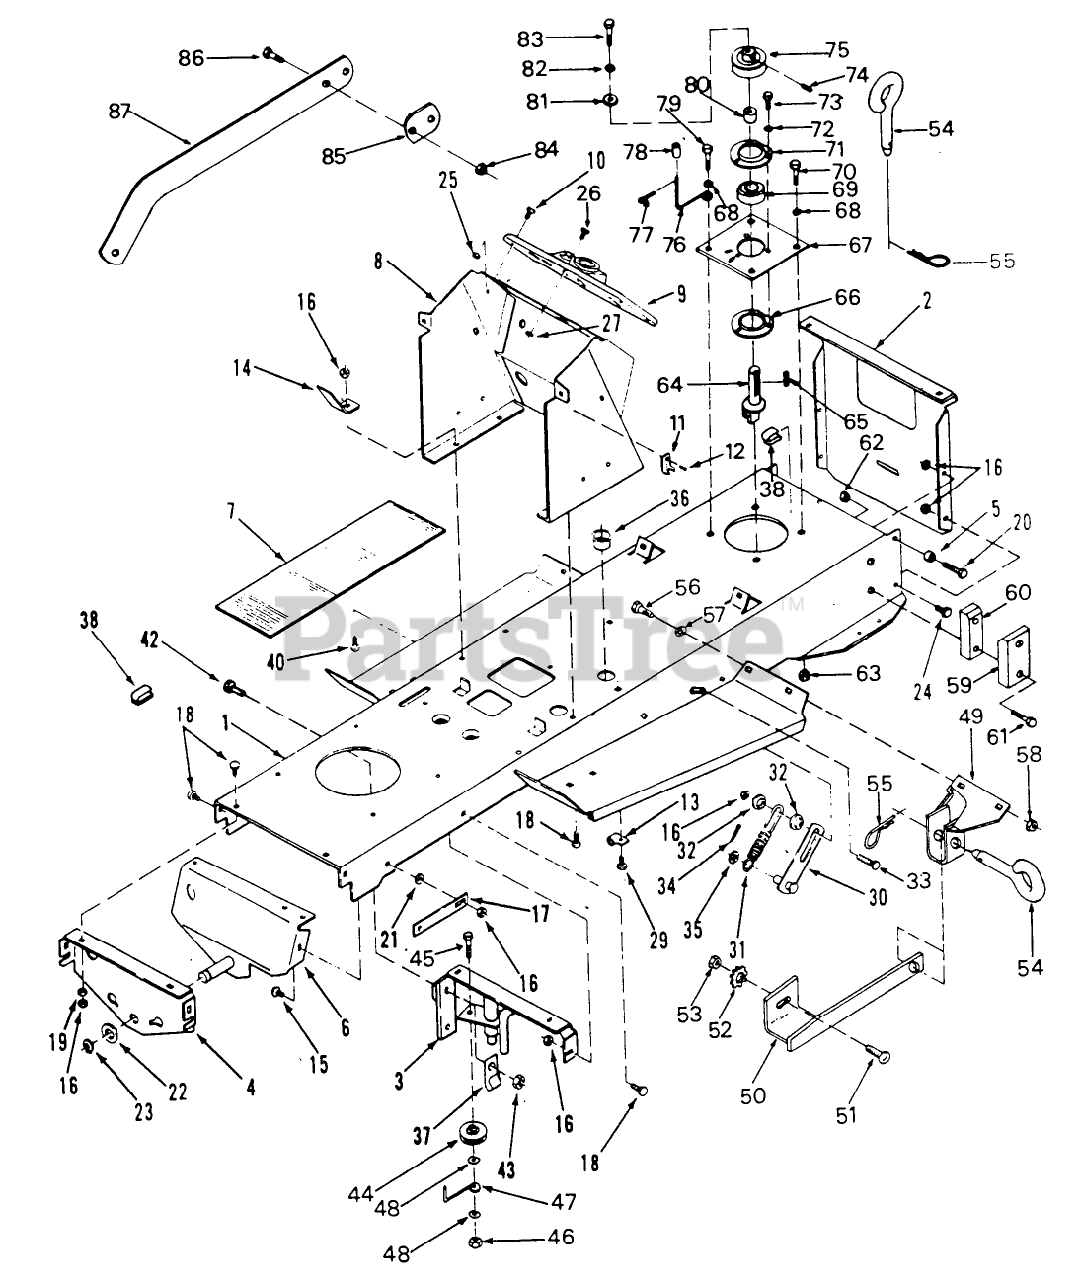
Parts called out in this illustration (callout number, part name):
2	PLATE-DRAWBAR *R
4	PLATE SUPT - AXLE *R
5	BEARING CAM ROLLER
7	PAD-FOOTREST
8	HOODSTAND ASSY *B
13	J-CLIP
17	STRAP *R
19	WASHER 5/16 SAE
22	WASHER
31	SPRING
35	WASHER-FLAT
36	BUSHING-NYLON 1.093
37	CLIP
54	PIN-TOOL
55	Hairpin Cotter
57	WASHER-SPECIAL
64	SHAFT-DRIVE
65	KEY
66	BEARING-CUP W/NUTS
68	WASHER 5/16 SAE
71	BEARING-CUP
81	WASHER
